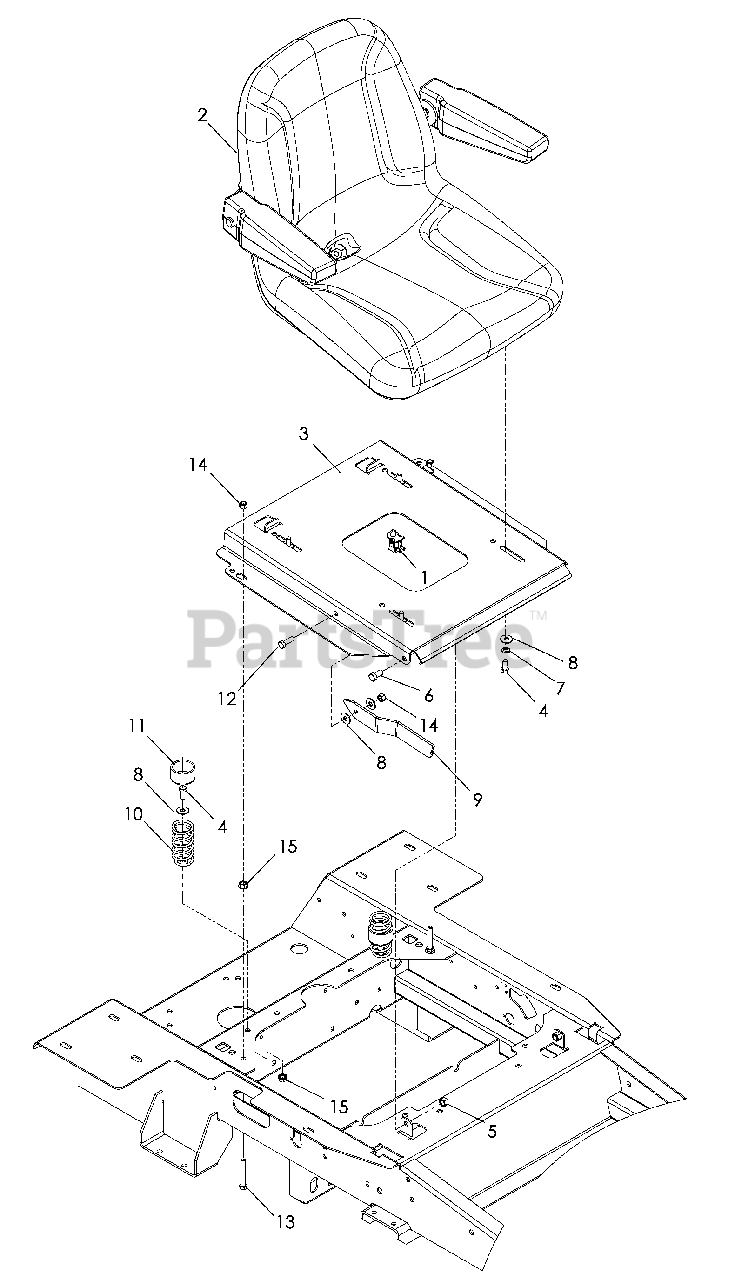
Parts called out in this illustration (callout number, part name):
1	SWITCH, SEAT
2	SEAT W/ARMREST
4	HCS 5/16-18 x ¾
5	NUT 3/8-16 NYLOC
6	HCS 3/8-16 x ¾
7	LOCKWASHER 5/16
8	WASHER 5/16
10	SPRING, SEAT
11	CAP, SPRING
12	HCS 5/16-18 x 1
13	HCS 5/16-18 x 2¼ TAP
14	NUT 5/16-18 NYLOC
15	NUT 5/16-18 WHIZLK
